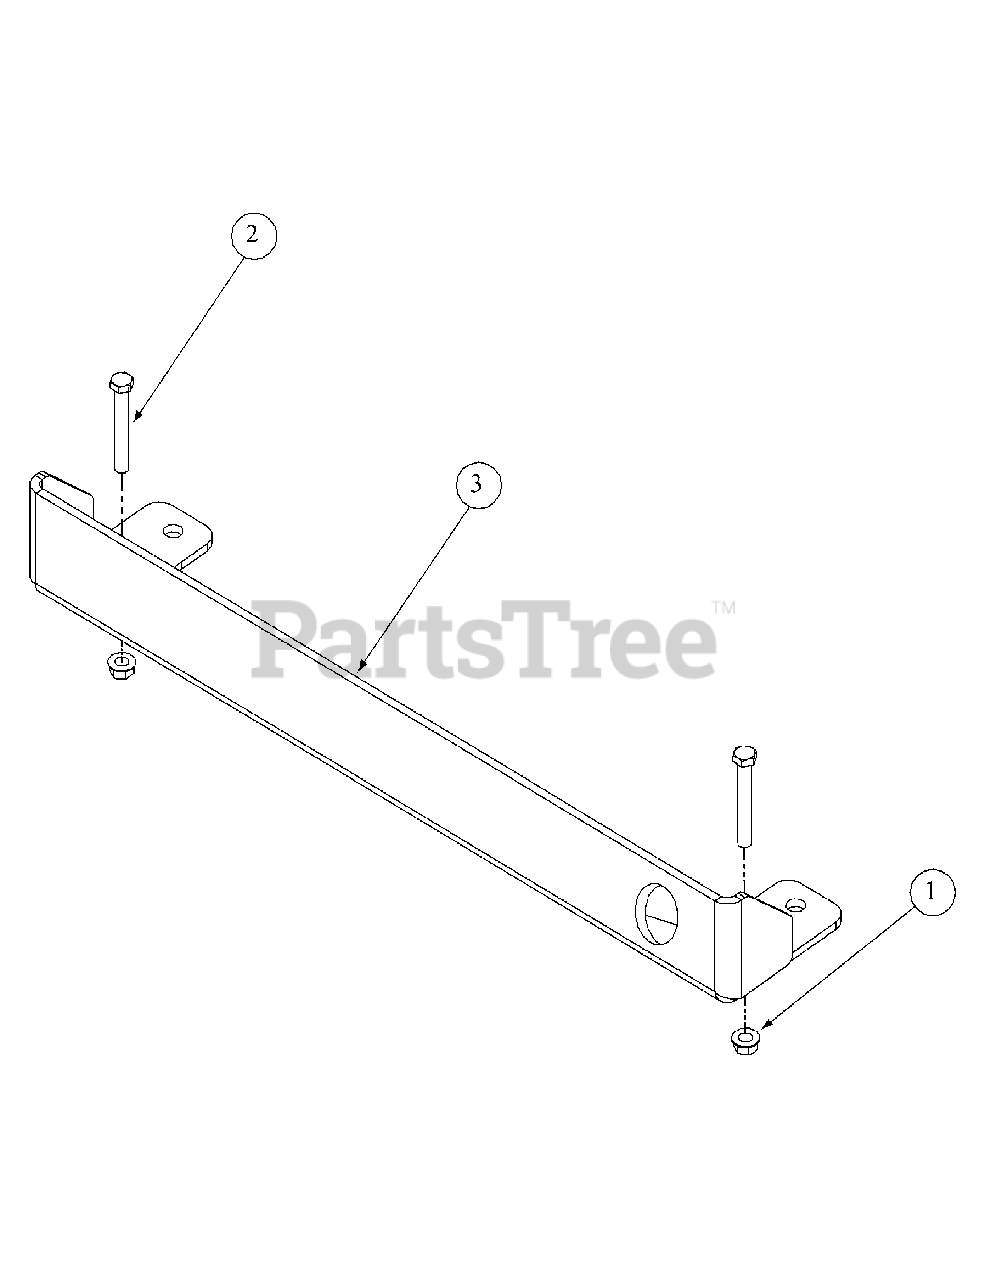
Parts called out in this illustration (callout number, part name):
1	Hex Nut, 1/2-13, Insert Lock
2	HHCS, 1/2-13, 3.00
3	Rear Bumper Plate
